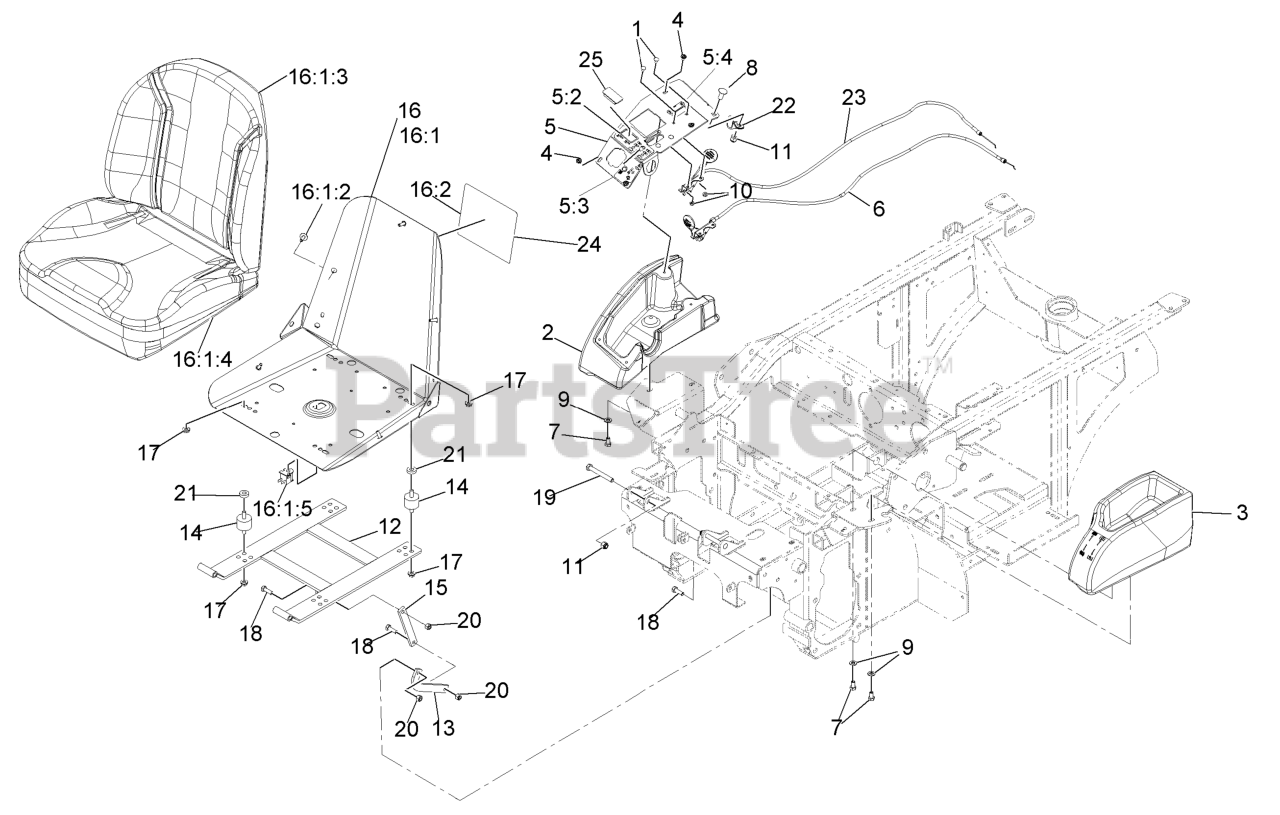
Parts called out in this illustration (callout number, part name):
1	Bolt-Carriage #10-24 X 1/2
2	Console-RH
3	Console, LH Grey
4	Screw-PPH #10-24 X 1/2
5	Control Panel ASM
5:2	Decal-Nav Console 640Kc
5:3	Decal-Speed Control
5:4	Decal-Choke
6	Cable-Throttle
7	Screw-HH 5/16-18 X 5/8
8	Bolt-Carriage 3/8-16 X 7/8
9	Washer-5/16 SAE
10	Nut-Nyloc #10-24
11	Nut-Nyloc 3/8-16
12	Frame-Seat
13	Link-Seat Stop
14	Mount-Vibration, Rubber
15	Link-Seat
16	ASM-Seat W/Decal
16:1	ASM-Seat, Navigator
16:1:2	Screw-HWH 1/4-20 X 3/4 Taptite
16:1:3	Cushion-Seat, Back
16:1:4	Cover-Seat Bottom Svc
16:2	Decal-Service Aid
17	Nut-Whizlock 5/16-18
18	Screw-HH 5/16-18 X 1
19	Screw-HH 3/8-16 X 3
20	Nut-Nyloc 5/16-18
21	Spacer
22	Clip-Loom
23	Cable-Choke
24	Decal-Service Aid
25	Plug-Hole
